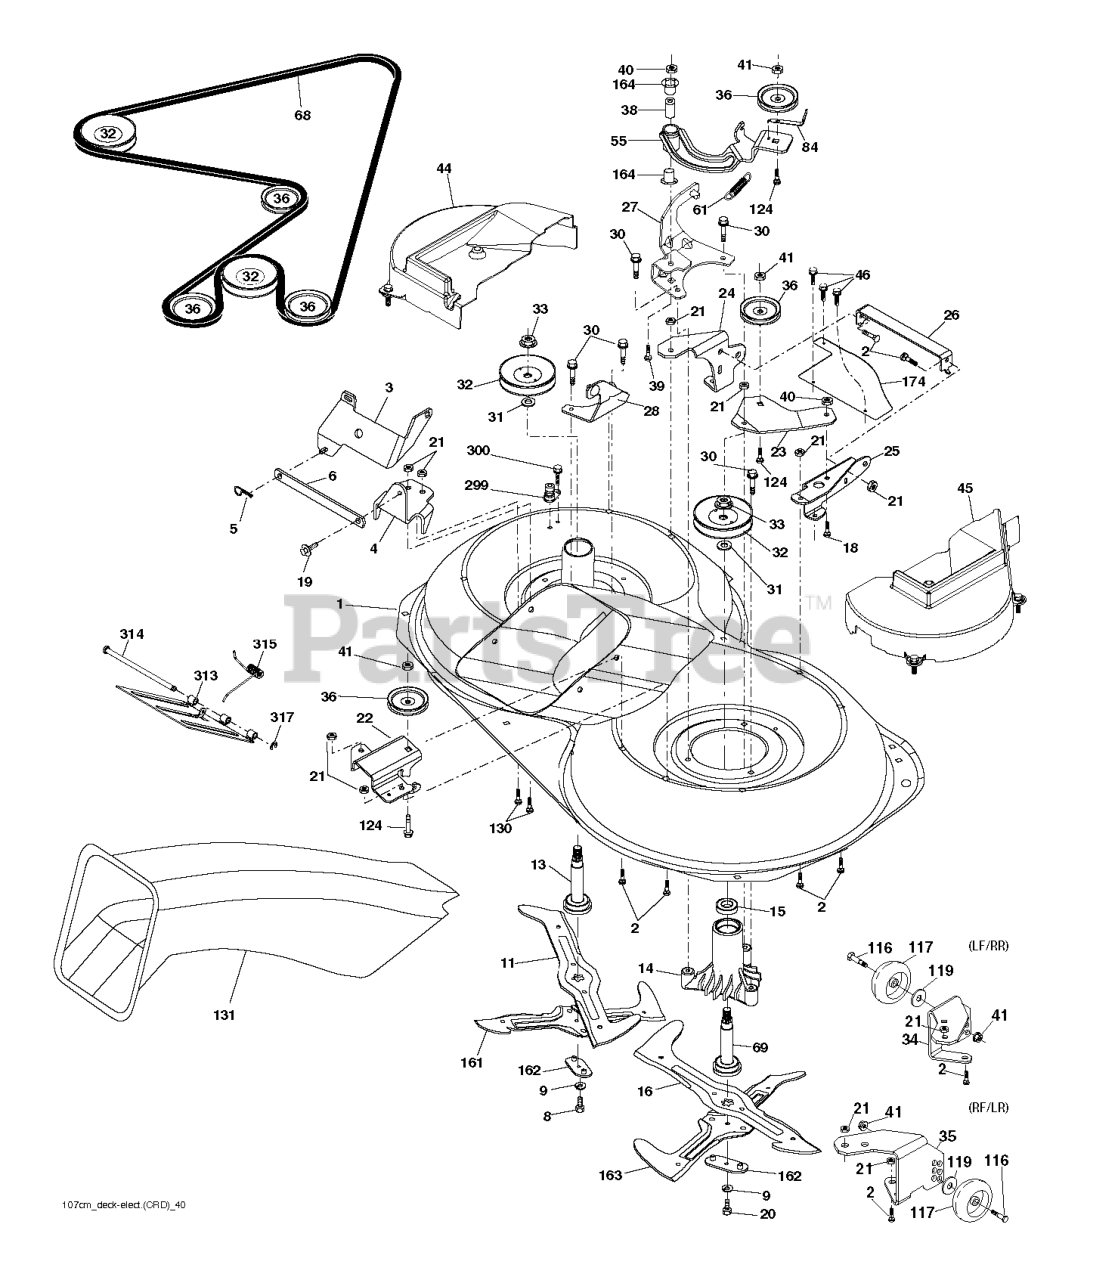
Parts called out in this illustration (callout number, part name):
2	RP BOLT 5/16-18 X3/4 ZN/YEL GR
3	BRACKET.ASM.BAR.SWAY.CHASS
5	RETAINER-SPRNG RB
6	BAR.SWAY.92.CRD
8	BOLT.3/8-24X1.25 GR8
9	LOCKWASHER
11	BLADE.3N1.LH.CRD
13	SHAFT ASM VENT
14	HOUSING.MANDREL.VENTED (MACHD)
16	BLADE.3N1.RH.CRD
19	BOLT SHD 5/16-18
20	BOLT.3/8-24X1.25GR8. LHTHRD
21	LOCKNUT
22	BRACKET.IDLER.RR.107.CRD
24	BRACKET
25	BRACKET RF
26	SUPPORT
28	BRACKET
30	SCREW, WASHER HEAD
31	WASHER.SPACER.MANDREL
32	PULLEY.MANDREL.4.80 PD.2006
33	NUT.FLANGE.LOCK.TOP
34	BRACKET
35	BRACKET
36	PULLEY.IDLER.4.25
41	NUT LOCK FLG 3/8-16 UNC
44	COVER MANDREL LEFT
45	COVER MANDREL RIGHT
46	SCREW.1/4-20X5/8
55	ARM.IDLER.107.CRD
61	SPRING
68	HEX-BELT 107 MOWER
69	SHAFT.ASM.W/LWR.BRG.RH.THREAD
84	KEEPER, BELT IDLER
116	BOLT.SHOULDER.3/8-16X3-5/8.
117	RP WHEEL. GUAGE RALLY
119	WASHER
124	BOLT.3/8-16X1.50
130	BOLT.CARR.SQNK.5/16-18UNC.X3/4
163	BLADE.CROSS.RH.CRD.107
164	BRNG T
174	PLATE
299	PORT.WASHOUT
300	SCREW.TT.#10-32X.5.3/8.FLANGE
313	COVER DOOR.107 CM CRD EZ MULCH
314	PIN PIN.HINGE
317	E-RING.5/16"
